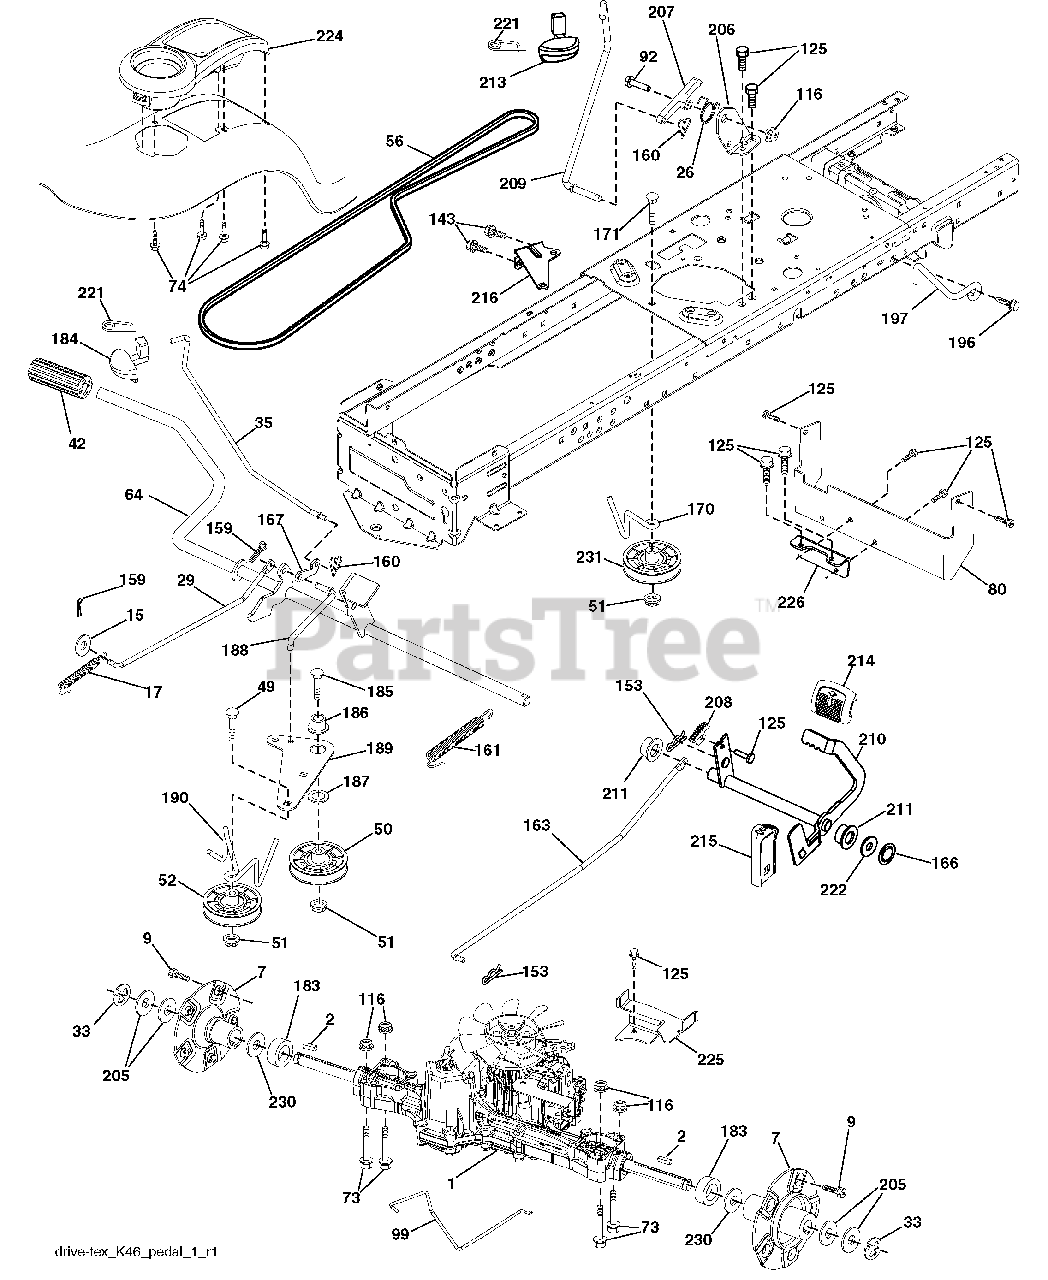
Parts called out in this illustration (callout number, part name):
1	Transaxle, Tufftorq K46BN
2	Key
7	Hub Asm.
9	Bolt Hub Wheel
15	Washer 13/32 x 13/16 x 16 Ga.
17	Spring, Brake
26	Spring Return Cruise
29	Rod, Brake
33	Ring E
35	Rod, Brake, Park
42	Cover, Foot Pedal
49	Bolt
50	Pulley Idler Flat
51	Lock Nut 3/8-16
52	Idler V-Groove 910" Offset
56	V-Belt, Drive
64	Shaft Asm. Pedal Brake Control
73	Bolt Hex 5/16-18 Gr. 5
74	Screw Hex Wsh. HI LO 1/4 x 1/2 unc
80	Strap Torque
92	Bolt Fin Hex 5/16-18 unc x 1.25
99	Rod Bypass
116	Nut Lock Hex Flange 5/16-18
125	Screw 5/16-18 x 3/4
143	Screw Thdrol 5/16-18 x 1/2
153	Retainer Spring
159	Pin Cotter 1/8 x 3/4
160	Retainer Clip
161	Spring, Return, Clutch
163	Rod Pedal Control
166	Nut Push .625
167	Latch Brake Parking
170	Keeper Belt Centerspan
171	Bolt
183	Spacer Axle
184	Handle Parking Brake
185	Bolt
186	Spacer Retainer
187	Washer
188	Link Clutch Ground Drive
189	Bellcrank Ground Drive
190	Keeper Bellcrank Ground Drive
196	Screw 3/8-16 x 1
197	Link Clutch Anti Rotation
205	Washer 25/32 x 1-5/8 x 16 Ga.
206	Bracket Mount Latch Cruise
207	Latch Control Cruise
208	Gear Sector Control Cruise
209	Rod Control Cruise
210	Rocker Asm. Pedal Control
211	Bearing Nylon
213	Knob Control Cruise
214	Pad Pedal Forward
215	Pad Pedal Reverse
216	Bracket Pulley Idler
221	Retainer Spring Clip Handle
222	Washer 21/32 x 1-1/4 10 Ga.
224	Console Toolbox
225	Keeper Belt Transaxle
226	Bracket Mount Torque
230	Washer Harden .793 x 1.637 x 060
231	Idler V-Groove
